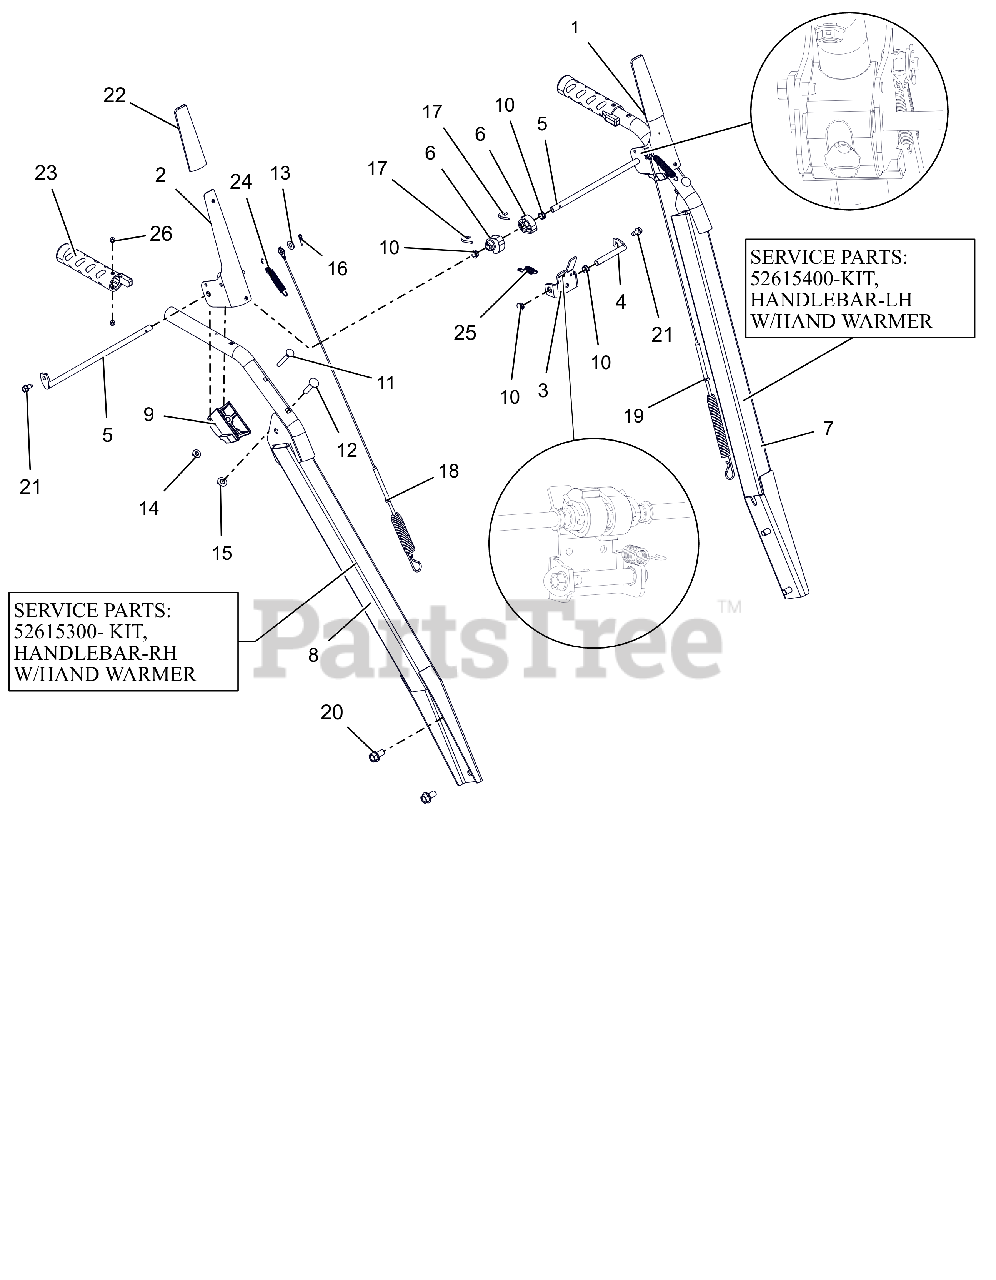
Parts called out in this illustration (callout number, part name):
1	LEVER, CLUTCH-LH
2	LEVER, CLUTCH-RH
3	BRACKET, INTERLOCK ARM
4	ROD, PIVOT - INTERLOCK
5	ROD, PADDLE MOUNT - PRO
6	CAM, INTERLOCK
7	HANDLEBAR, HEAVYDUTY-PRO LH
7	KIT, HANDLEBAR-LH W/WARM GRIP
8	HANDLEBAR, HEAVYDUTY-PRO-RH
8	KIT, HANDLEBAR-RH W/WARM GRIP
9	BLOCK, CLUTCH PADDLE
10	BUSHING, POLYLINER-.38 SNAPIN
11	BLT-RDHDXLSQNK .25-20X2.0 G5YZ
12	@BLT-RDHDSQNK .31-18X1.50 G5YZ
13	@WSHR-FL-STL.281X.62X.065 YWZC
14	@NUT-LK-CTR-FLG .25-20 YWZC
15	@NUT-LK-TOP-FLG .31-18 YWZC
16	PIN-HAIR INT .06X.18X.77
17	PIN, SPRING CLIP
18	CABLE, AUGER (DELUXE & PRO)
19	CABLE, UPPER TRACTION
20	BLT-SERHFWH .38-16X.75 YWZC
21	SCR-TAP .25-20X.50 HWH TR YWZ
22	SLEEVE, CLUTCH PADDLE-GRAY
23	GRIP,HEATED HANDLE-GRAY
24	SPRING, EXTENSION
25	SPRING-EXT .047X.438X1.45
26	RVT-POP #43 .125X.313 STL ZINC
